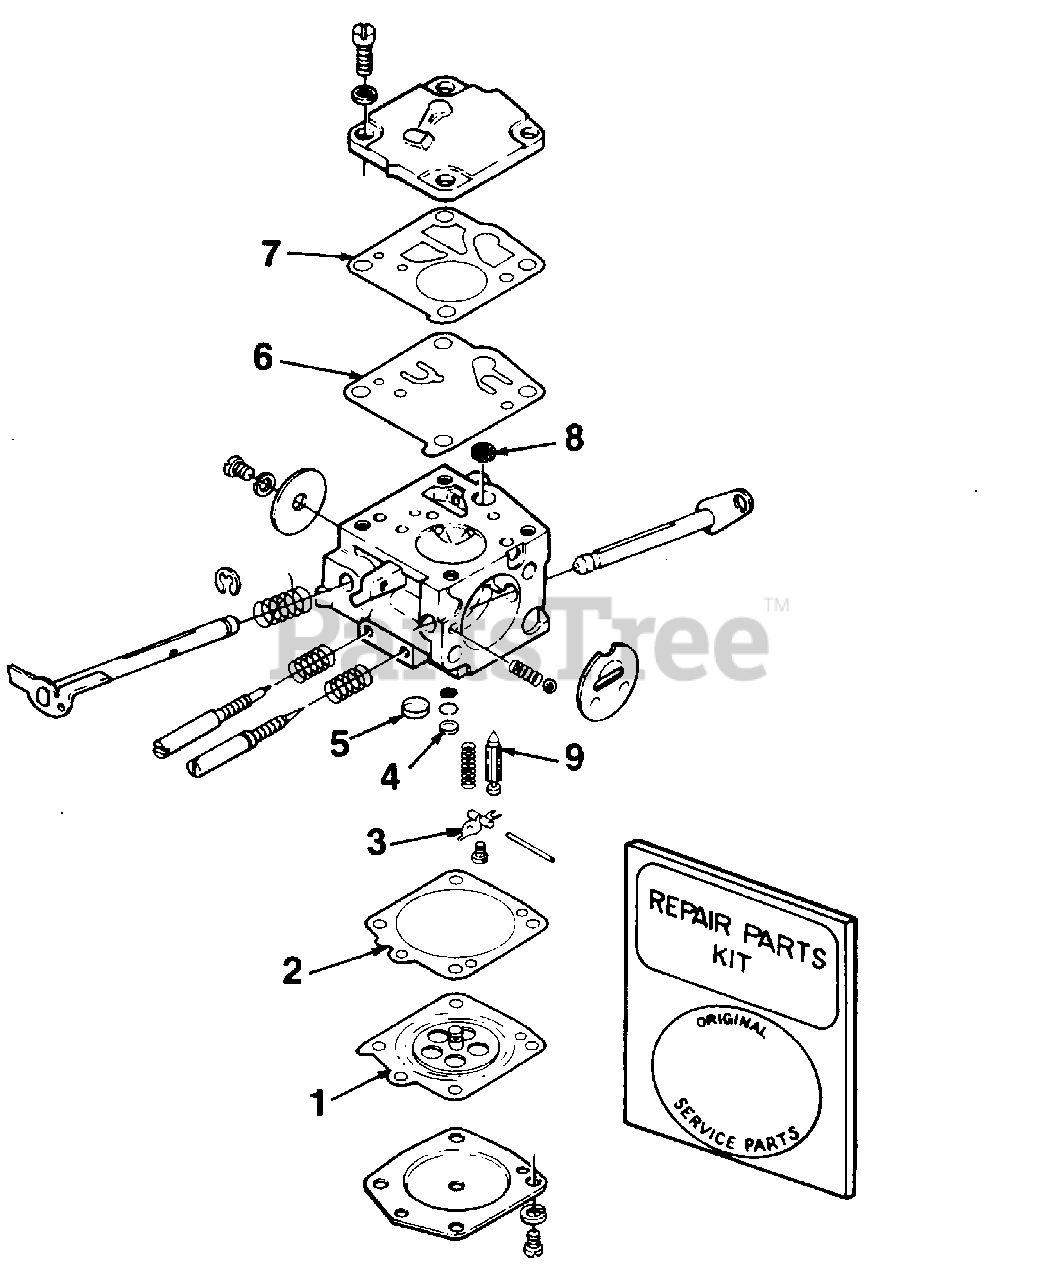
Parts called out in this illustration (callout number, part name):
1	Repair Kit
2	Repair Kit
3	Repair Kit
4	Repair Kit
5	Repair Kit
6	Repair Kit
7	Repair Kit
8	Repair Kit
9	Repair Kit
